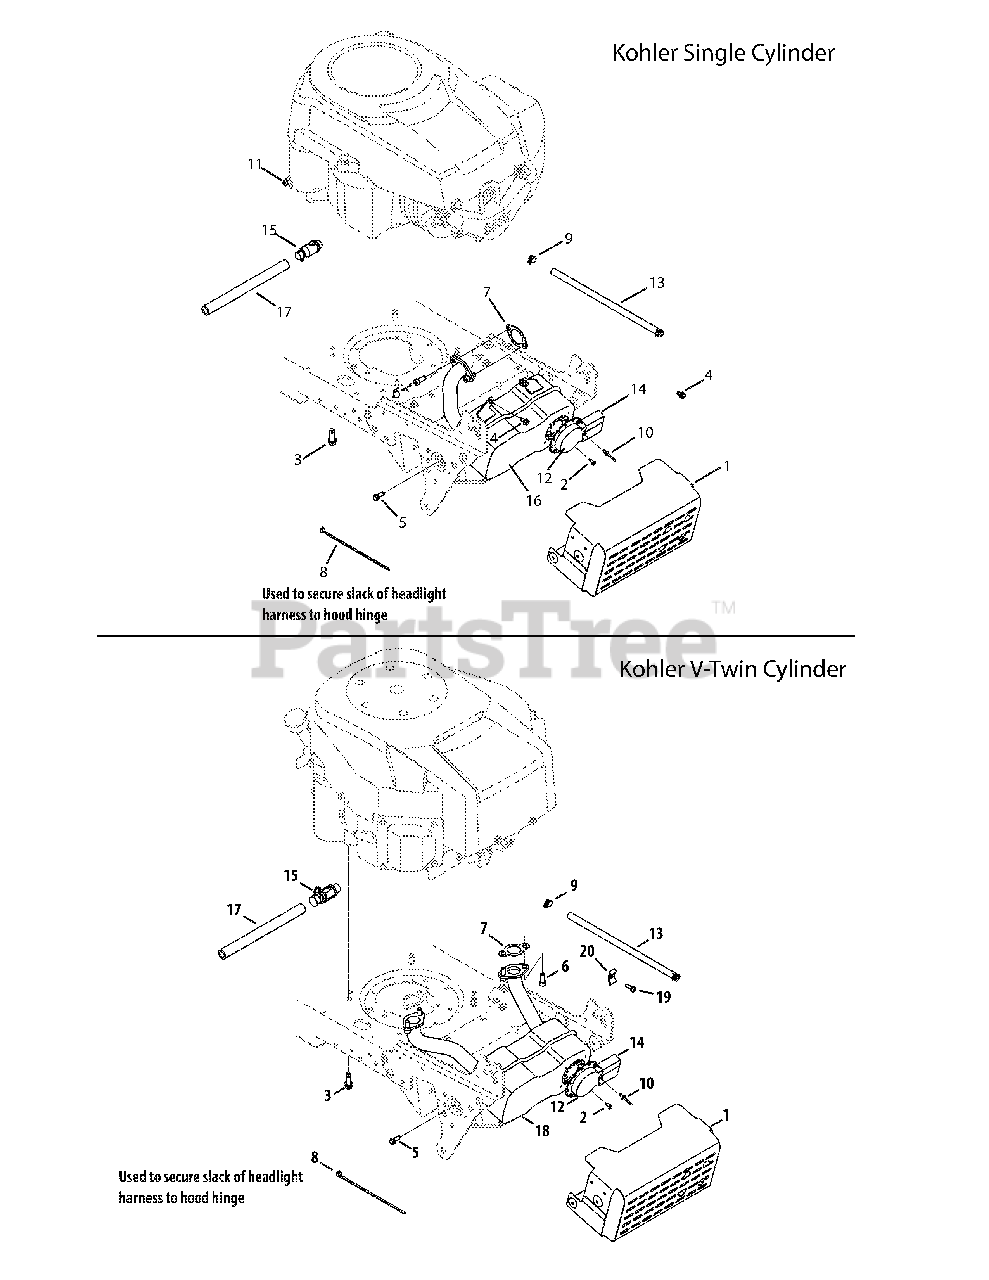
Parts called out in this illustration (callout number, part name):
1	Shield, Muffler
2	Screw, #8-18, 0.500
3	Screw, Hex, 3/8-16 x 1.00
4	Screw, Hex, 1/4-20, 0.500
5	Screw, Hex, 1/4-20, 0.750
6	Screw, 5/16-18, 0.75
7	Exhaust Gasket
8	Cable, Tie, 3/16 x .05 x 7.4
9	Hose Clamp
10	Rivet, Pop, .188 x .325
11	Flat Washer, 1.031 x 1.620 x .095
12	Deflector, Muffler
13	Fuel Line, Low Permeation
14	Extension, Deflector
16	Muffler, Single Inlet
17	Extension Hose, Oil Drain
18	Twin Muffler, Kohler
19	Self-Tap Screw, M5 x 0.8 Torx
20	Conduit Dual Clamp, Kohler
